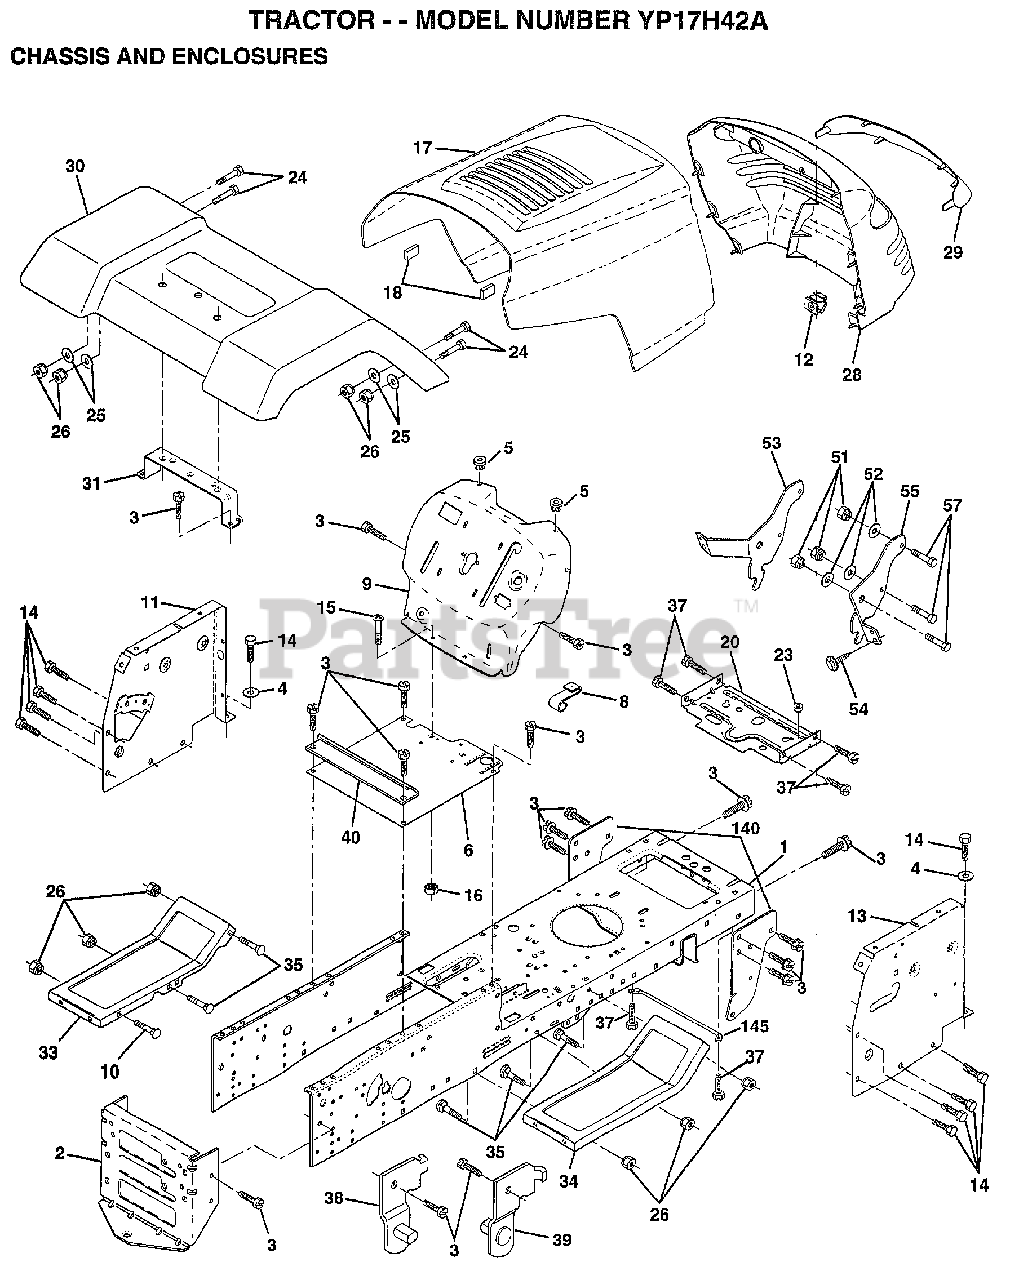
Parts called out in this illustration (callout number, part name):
1	CHASSIS.STAMPING
3	SCREW
4	WASHER
5	BUMPER-HOOD/DASH
6	SADDLE
8	CLIP.RETAINER
9	DASH.SILKSCREEN
11	"PANEL-DASH,LH"
12	CLIP.TINNERMAN
13	PANEL.ASM.DASH.RH
14	SCREW
17	"HOOD W/TRIM,MS428"
20	"PLATE-MTG,BATT/FU"
24	BOLT
25	WASHER
26	NUT
28	GRILL
29	GRILLE.LENS
30	FENDER.LTST.WLDMNT.W/SHIFT
31	BRACKET SUPT FEND
33	FOOTREST PNT LH
34	FOOTREST.RH.LT/GT
35	BOLT
37	SCREW LT
38	BRACKET ASM LH
39	BRACKET ASM RH
40	SPACER FENDER LT
51	NUT
52	WASHER
53	BRACKET.GRILLE.LH
54	SCREW.HEX.WS.HD
55	BRACKET.GRILLE.RH
140	BRKT SUSPENSION
145	"ROD POVOT,CHASSIS"
